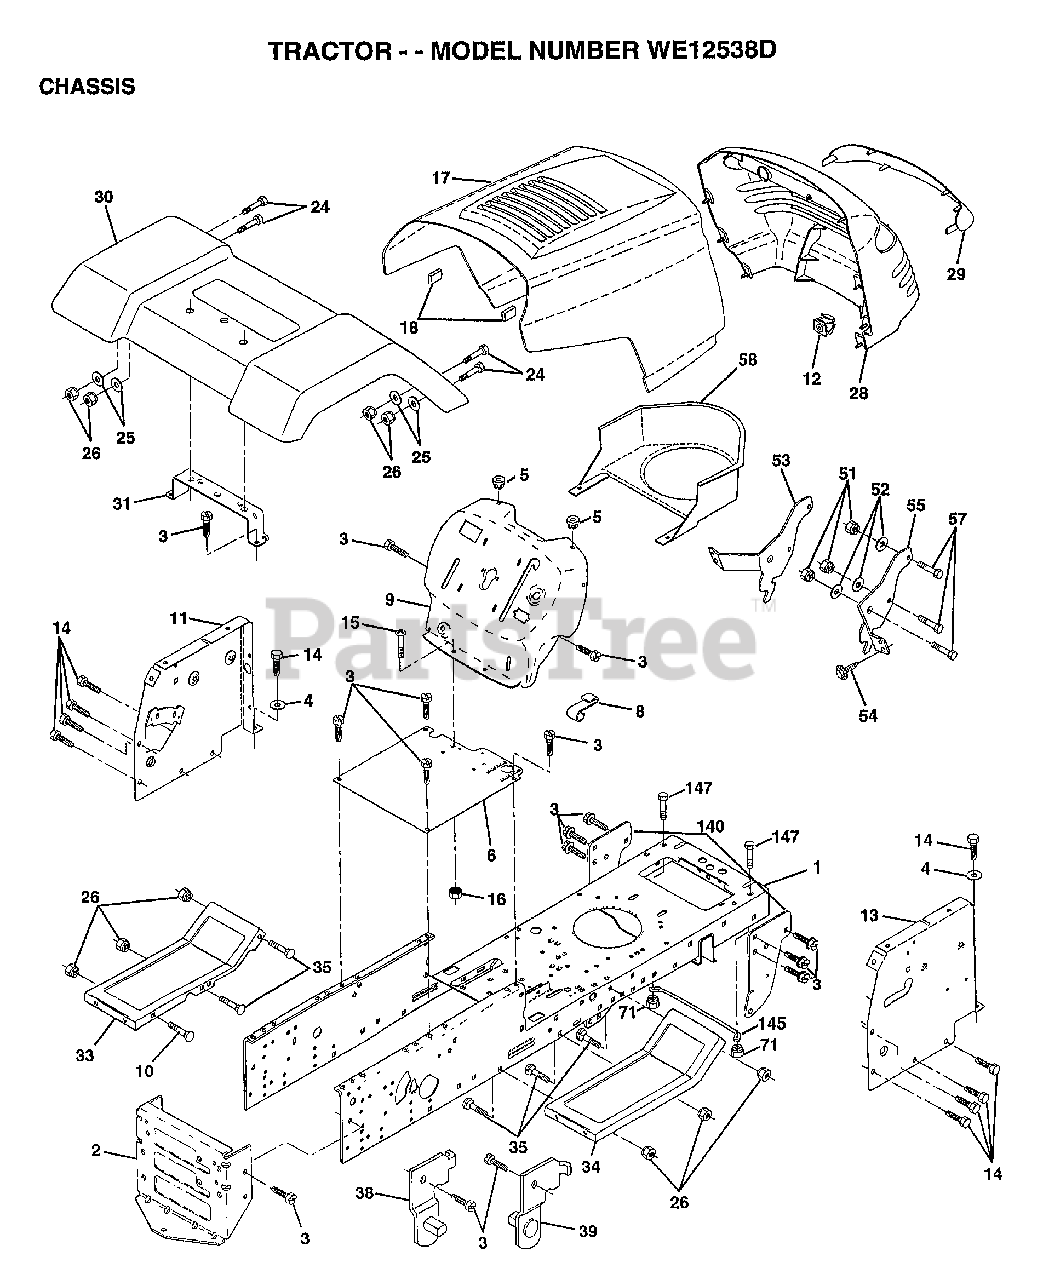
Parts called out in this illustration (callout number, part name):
1	CHASSIS ASM
3	SCREW
4	WASHER
5	BUMPER-HOOD/DASH
6	"SADDLE-SLKSCR,5SP"
8	CLIP.RETAINER
9	DASH.SILKSCREENED
11	"PANEL-DASH,LH"
12	CLIP.TINNERMAN
14	SCREW LT
15	SCREW
17	HOOD.STEEL.ASSY
24	BOLT
25	WASHER
26	NUT
28	GRILLE-MS428
29	LENS GRILLE
31	BRKT FENDER
33	FOOTREST.LH.PERF.
34	FOOTREST.RH.PERF.
35	BOLT
38	BRACKET ASM LH
39	BRACKET ASM RH
51	NUT
52	WASHER
53	BRACKET.GRILLE.LH
55	BRACKET.GRILLE.RH
57	BOLT
58	AIR DUCT
140	BRKT SUSPENSION
145	"ROD POVOT,CHASSIS"
147	BOLT LT
